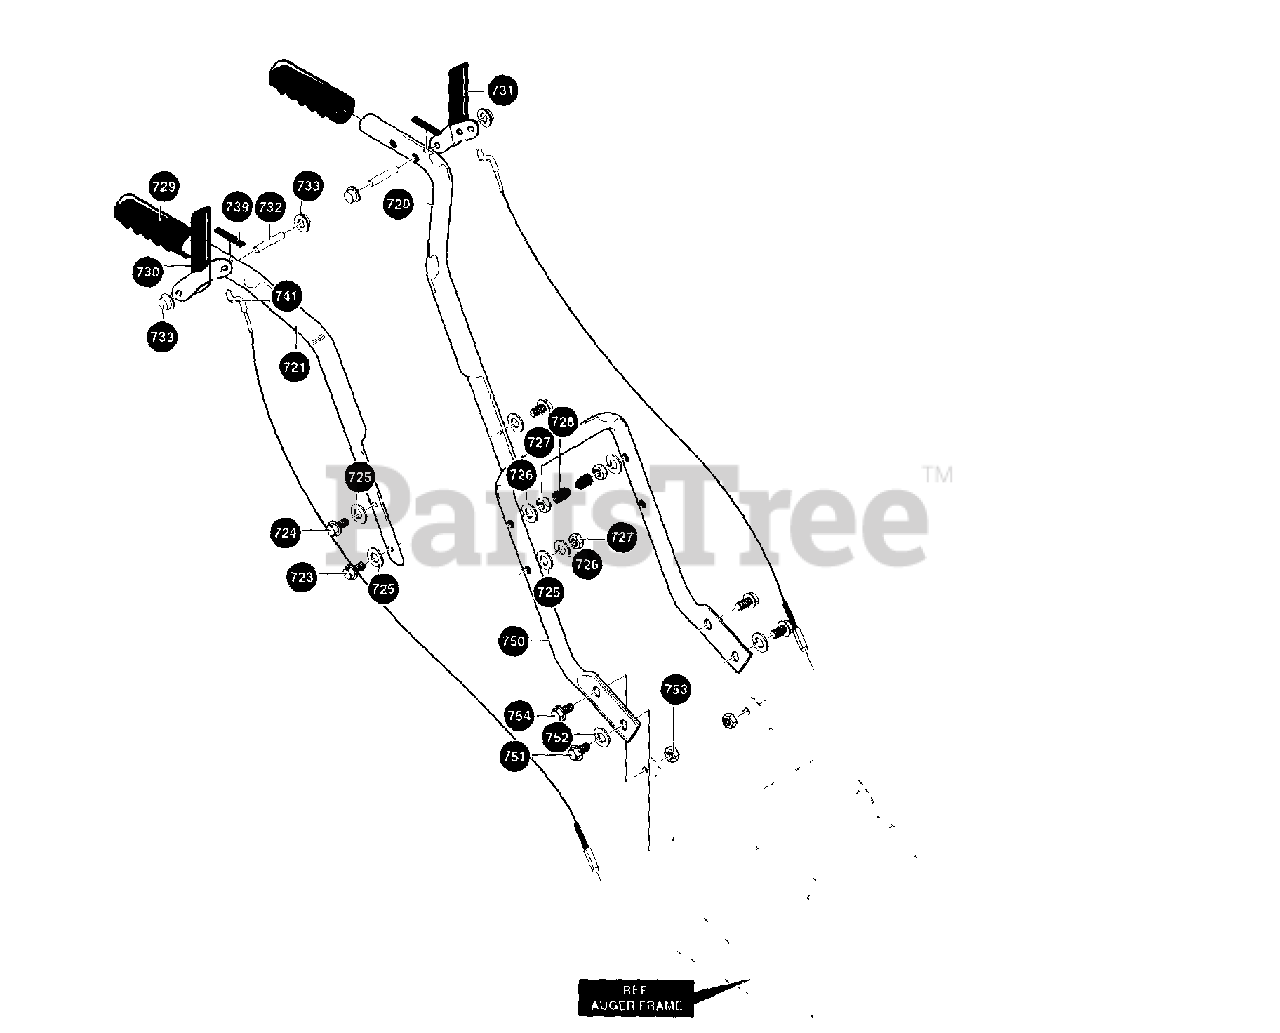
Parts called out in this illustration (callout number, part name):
720	HANDLE, UPPER LH
721	HANDLE, UPPER RH
723	SCREW, 3/8-16 X 2.00
724	SCREW, 3/8-16 X 3.00
725	FLATWASHER .406 X .81 X .065
726	WASHER, .393 X .68 X.10
727	NUT, 3/8-16
728	STOP, PLASTIC
729	GRIP, HANDLE
730	HANDLE-CLUTCH
731	HANDLE, ASSY CL LH
732	PIN, PIVOT
733	NUT, PUSH ON CAP
739	BUMPER, RECT
741	CABLE, CLUTCH
750	HANDLE, LOWER
751	SCREW, 5/16-18 X .50
753	NUT, 5/16-18
754	SCREW, 5/16-18 X .75
